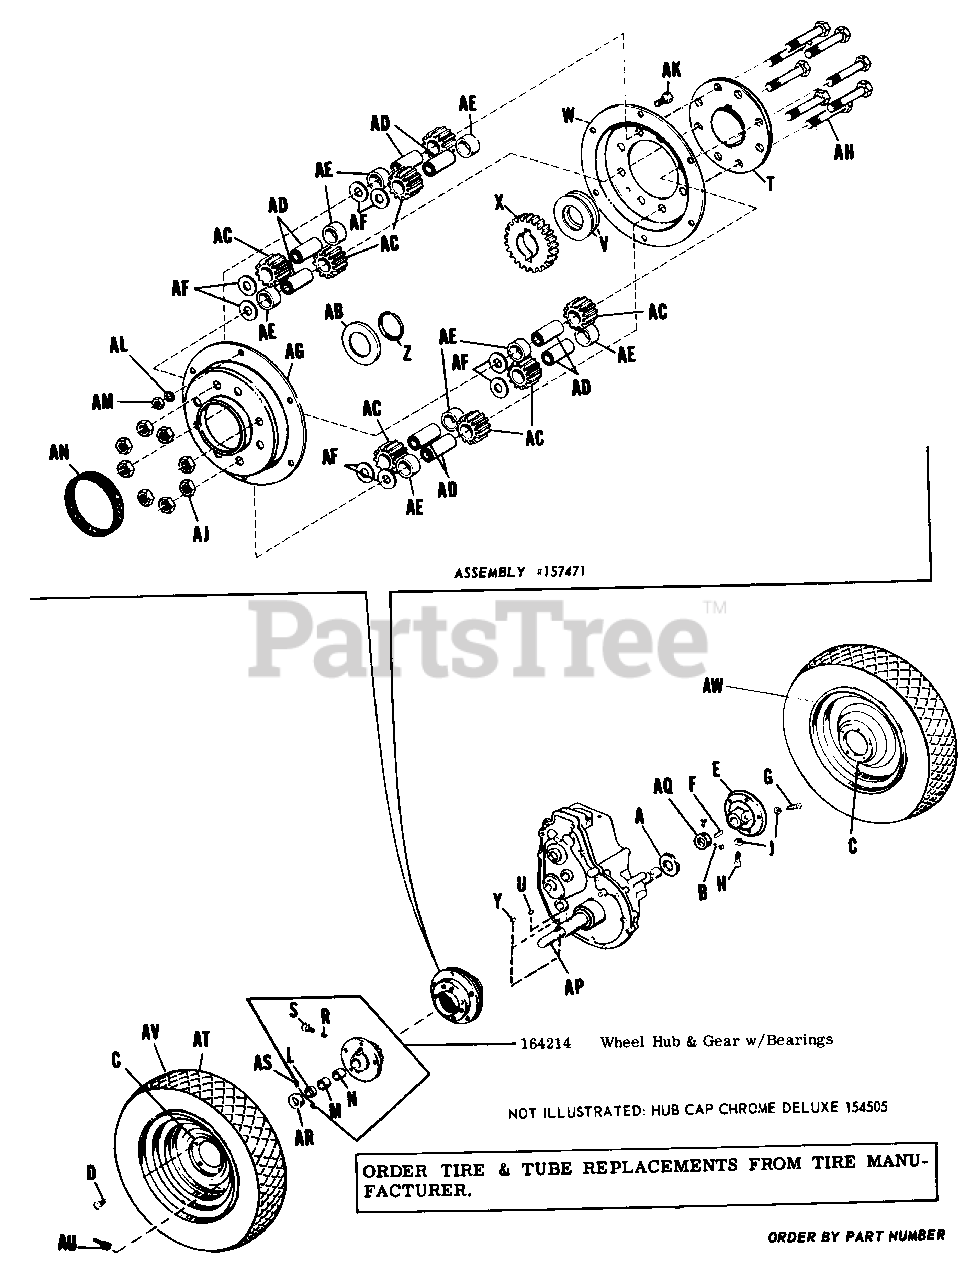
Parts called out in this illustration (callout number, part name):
B	Set Screw, 5/16"-18 x 3/8" lg.
C	Wheel Drive
E	L.H. Wheel Hub
G	Set Screw, 3/8"-16 x 1-1/2" lg.
H	Set Screw, 3/8"-16 x 1" lg.
J	Hex. Jam Nut, 3/8"-16
M	Nylon Bearing
R	Nylong Plug
S	Control Traction Bolt 7/16"-20 x 1/2" lg.
T	Differential Carrier
V	Axle Washer
W	Differential Cover
X	Differential Gear
Y	Hi-Pro Key
Z	Retaining Ring
AB	Axle Washer
AC	Differential Pinion
AD	Pinion Differential Spindle
AE	Differential Spacer
AF	Plain Washer
AG	Differential Cover
AH	Hex. Cap Serew, 3/8"-16 x 2-1/2"
AJ	Full Lock Hex. Nut, 3/8"-16
AK	Hex. Cap Screw, 1/4"-20 x 5/8"
AL	Lock Washer, 1/4"
AM	Full Hex. Nut, 1/4"-20
AN	Differential Cover Seal
AQ	Axle Collar
AR	Axle Collar
AS	Set Screw, 5/16"-18 x 3/8"
AT	Tire 10-1/2 x 12
AU	Valve Stem
AV	Wheel & Tire Assy.
AW	Tube (For Service Only)
